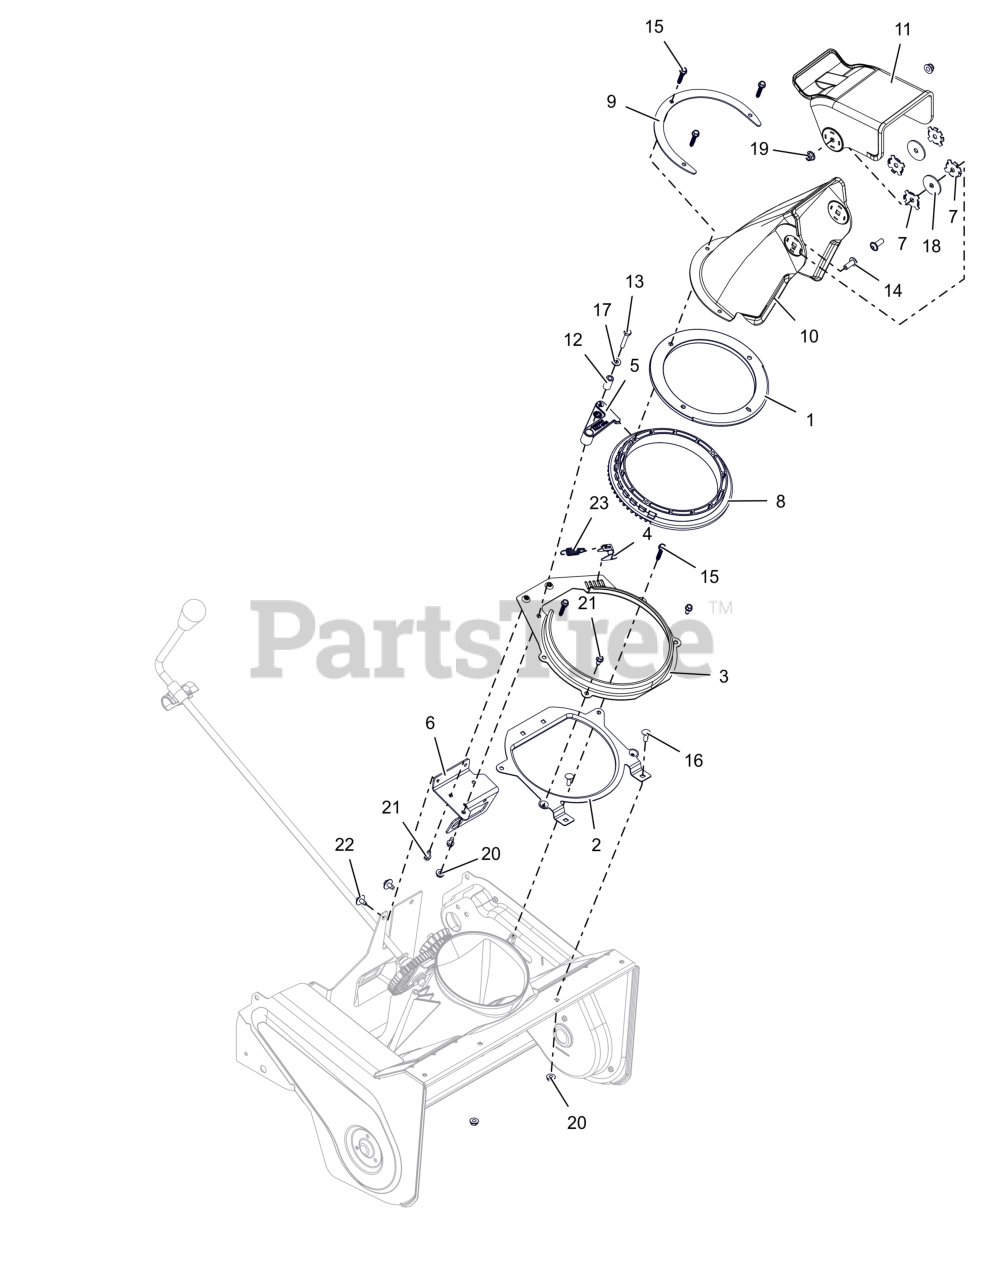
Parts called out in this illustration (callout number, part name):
1	GUARD, WATER
2	RING, CHUTE MOUNT - LOWER
3	RING, CHUTE MOUNT - UPPER
4	BRKT, SPRG
5	ARM, PAWL
6	BRKT, CHUTE ROTATION - REAR
7	PLATE, FRICTION
8	GEAR, CHUTE RING
9	BRKT, ROTATION - MANUAL
10	CHUTE, DISCHARGE-SINGLE STAGE
11	CAP, CHUTE-SINGLE STAGE
12	BSHG, SLV .265X.505X.995
13	BLT, HEX .25-20X1.50 G5 ZCC
14	SCR,BTN-FLG .31-18X0.875
15	SCR,PLASTITE .25-10X1.25 ZCC
16	BLT, RHSN .25-20X.750 G5 ZCC
17	WSHR,FLT .281X.625X.065 ZCC
18	WSHR,FRICTION-.332X1.525X.094
19	NUT,LK-NYL-FLG .31-18 G5ZC120
20	NUT-LK-TOP-FLG .250-20 GF ZCC
21	SCR-TAP .25-20X.50 HWH ZCC
22	SCR, TAP .25-20X.50 LG HWH ZCC
23	SPRG, TENSION .052X.520X1.74
